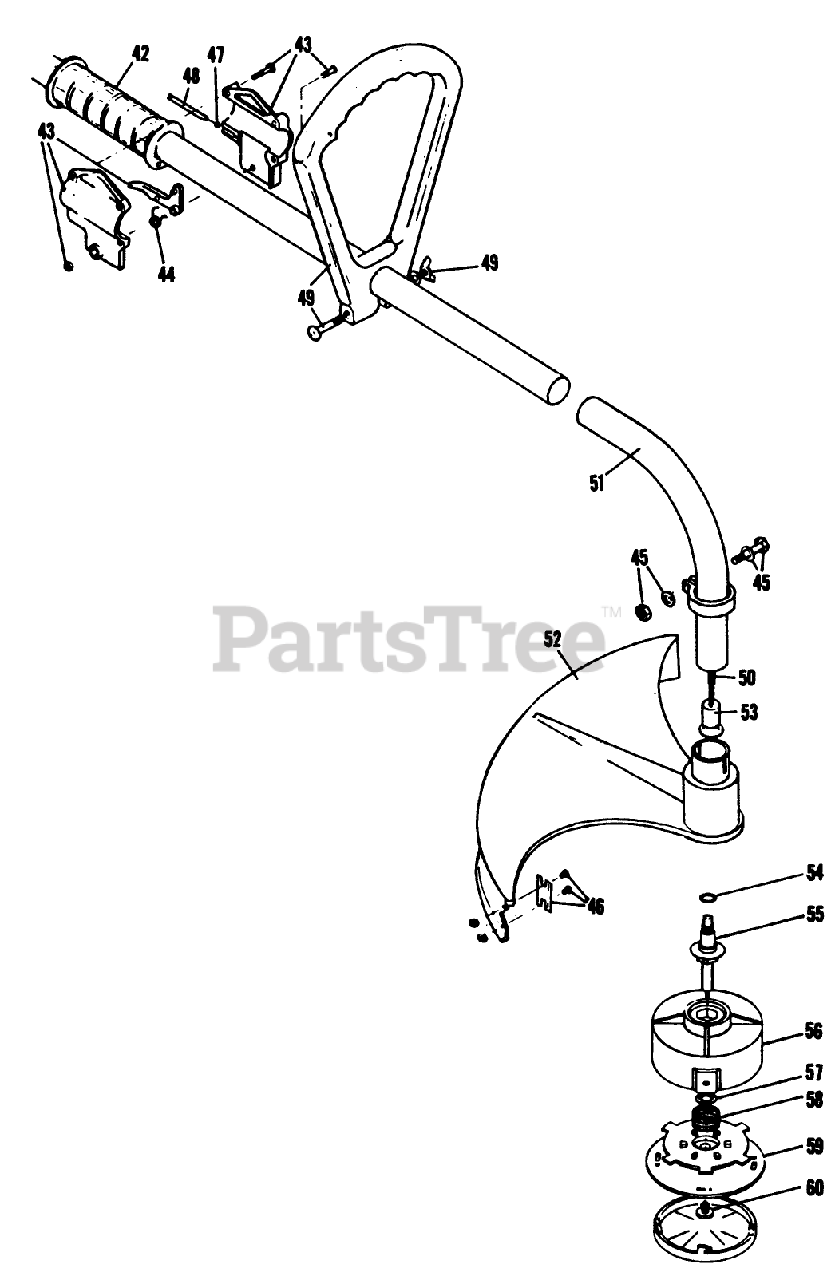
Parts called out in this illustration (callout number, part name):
42	Main handle grip
43	Throttle trigger assembly
44	Throttle trigger spring
45	Lower clamp assembly
46	Blade assembly
47	Throttle cable
48	Throttle cable housing assy.
49	Handle assembly
50	Flex drive shaft
51	Drive shaft housing assembly
52	Guard and bearing assembly
53	Drive shaft adaptor
54	Thrust washer
55	Drive shaft
56	Spool housing
58	Actuator spring
59	Cartridge spool
60	Thumb screw
